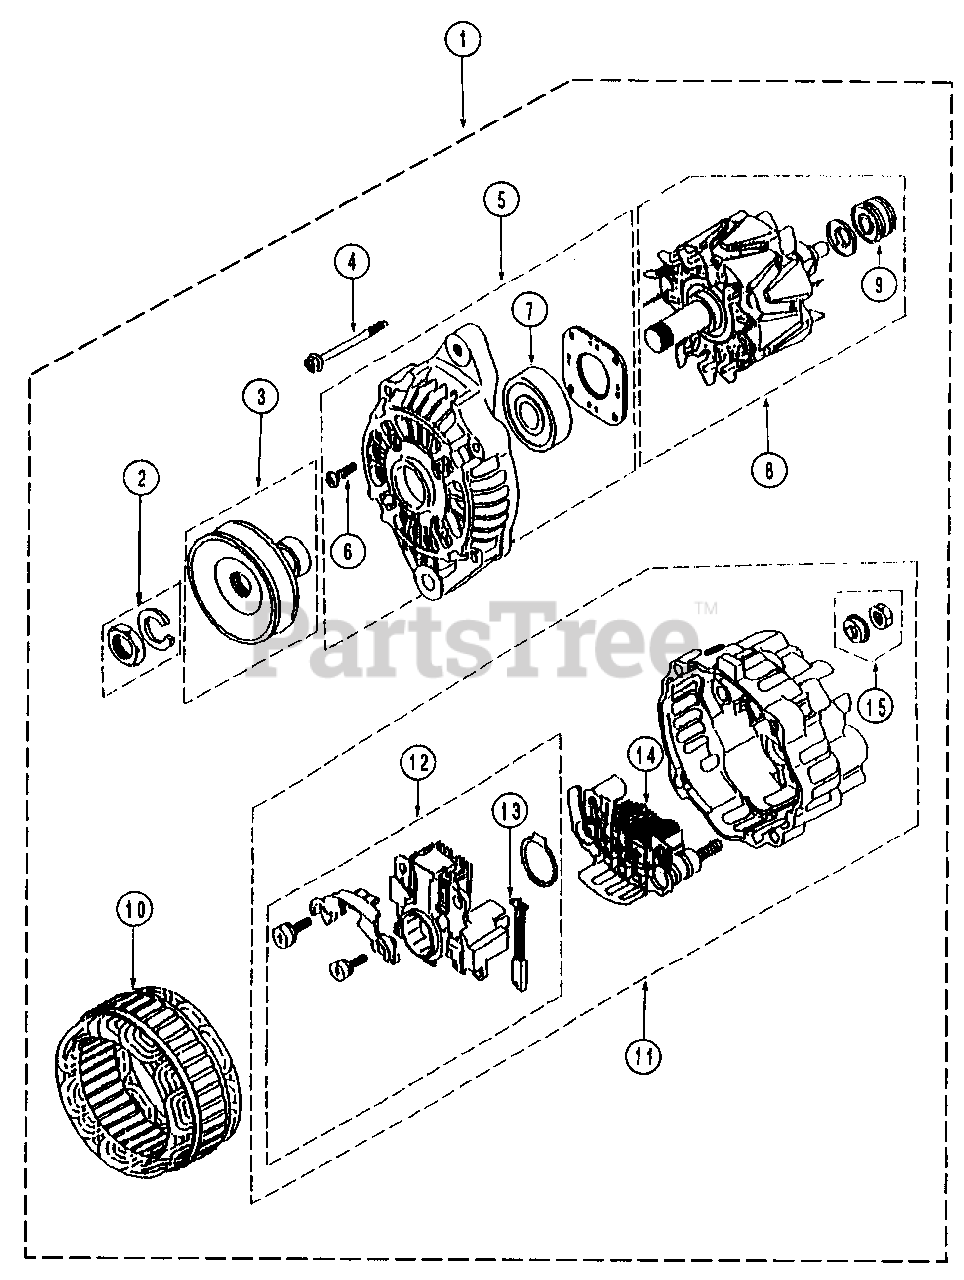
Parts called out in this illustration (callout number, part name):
1	Alternator Ass'y
2	Nut Set
3	Puller Ass'y
5	Bracket Ass'y, Front
7	Bearing, Front
9	Bearing, Rear
11	Bracket Ass'y, Rear
12	Regulator Set
14	Rectifier Ass'y
15	Nut Set
